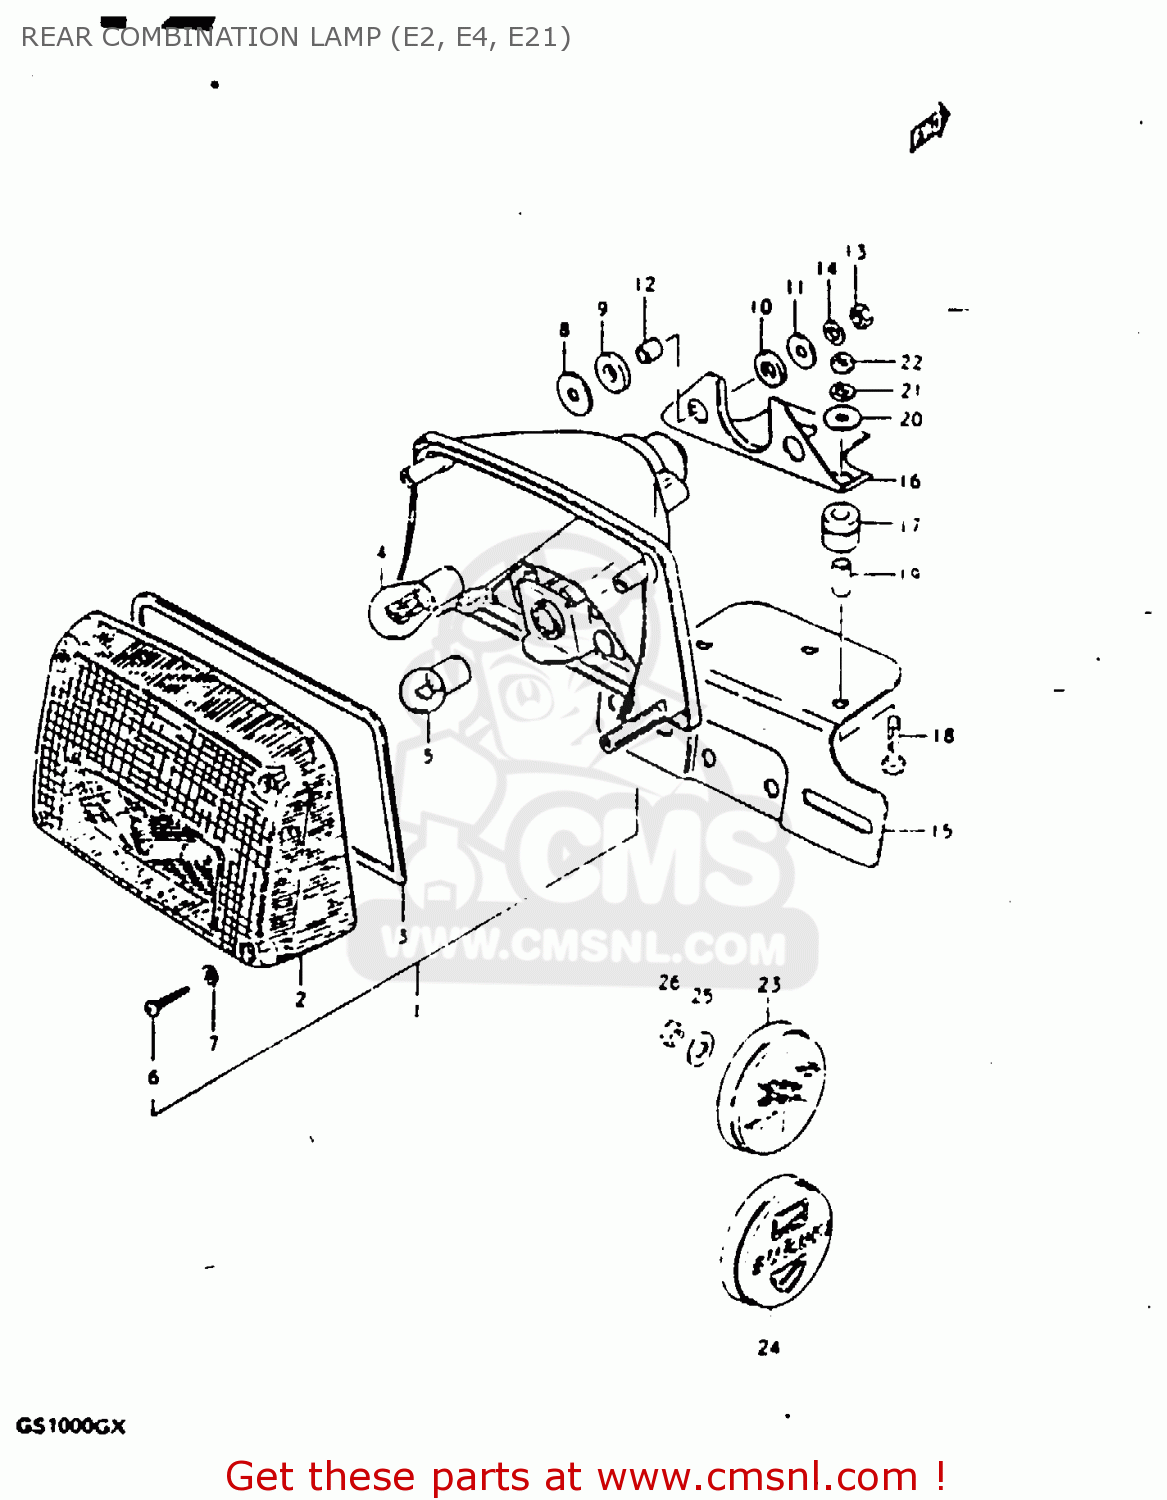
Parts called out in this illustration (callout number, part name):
1	LAMP, REAR COMBINATION
2	LENS
3	GASKET (NAS)
4	BULB 12V21/5W
5	BULB
6	SCREW,REAR COMBINATION LAMP
7	GASKET (NAS)
8	WASHER
9	CUSHION
10	CUSHION
11	WASHER(6,5X22X1.6)
12	SPACER(6.1X9X7.5)
13	NUT
14	LOCK WASHER
15	BRACKET, LICENCE PLATE
16	BRACKET,LICENSE PLATE
17	CUSHION, BRACKET
18	BOLT
19	SPACER (6.4X9X15.5)
20	WASHER
21	LOCK WASHER
22	NUT
23	REFLEX REFLECTOR,RR
24	EMBLEM, REAR SIDE
25	WASHER
26	NUT
